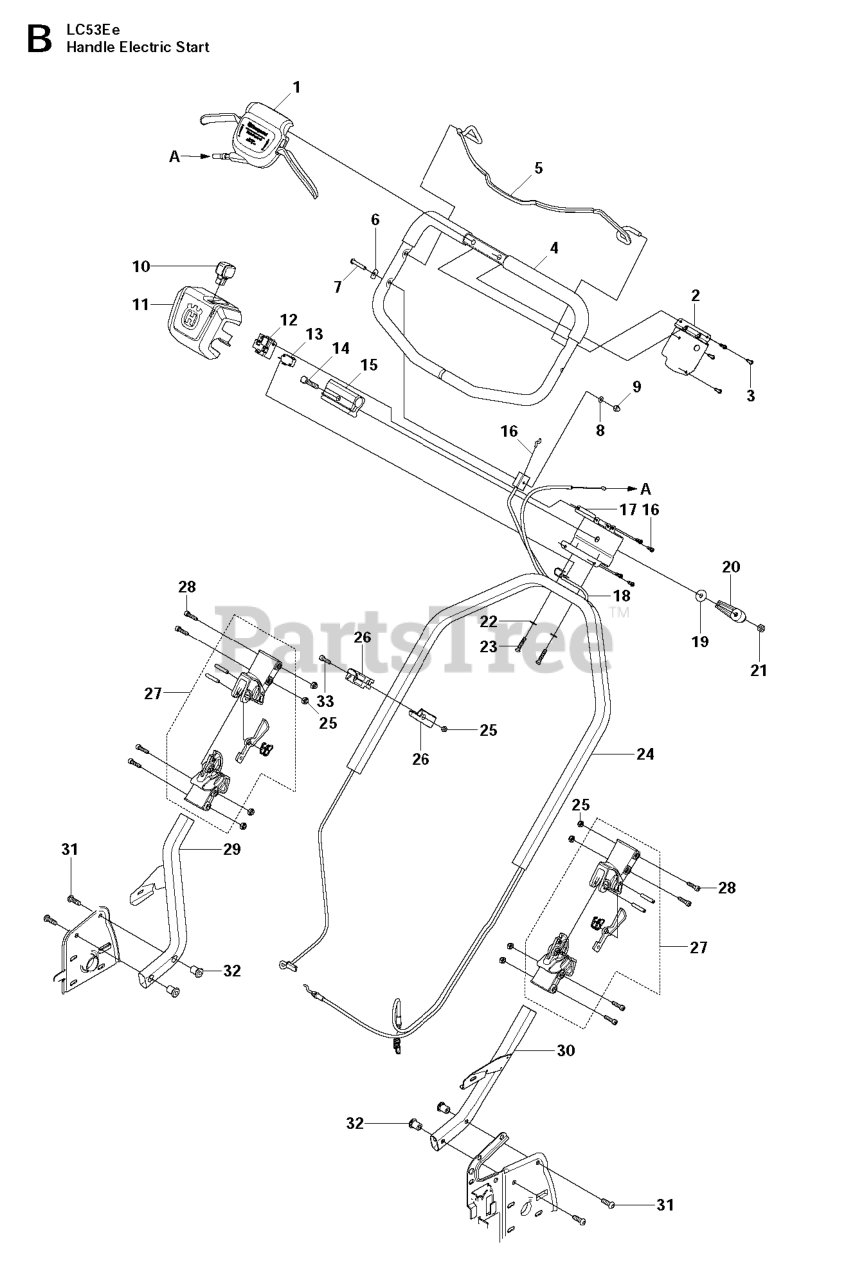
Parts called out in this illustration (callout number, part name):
8	WASHER - M6
19	WASHER - 25X8.5X2.3
28	REPL BY 725 53 74-55
33	SCREW MC6S 6X20
